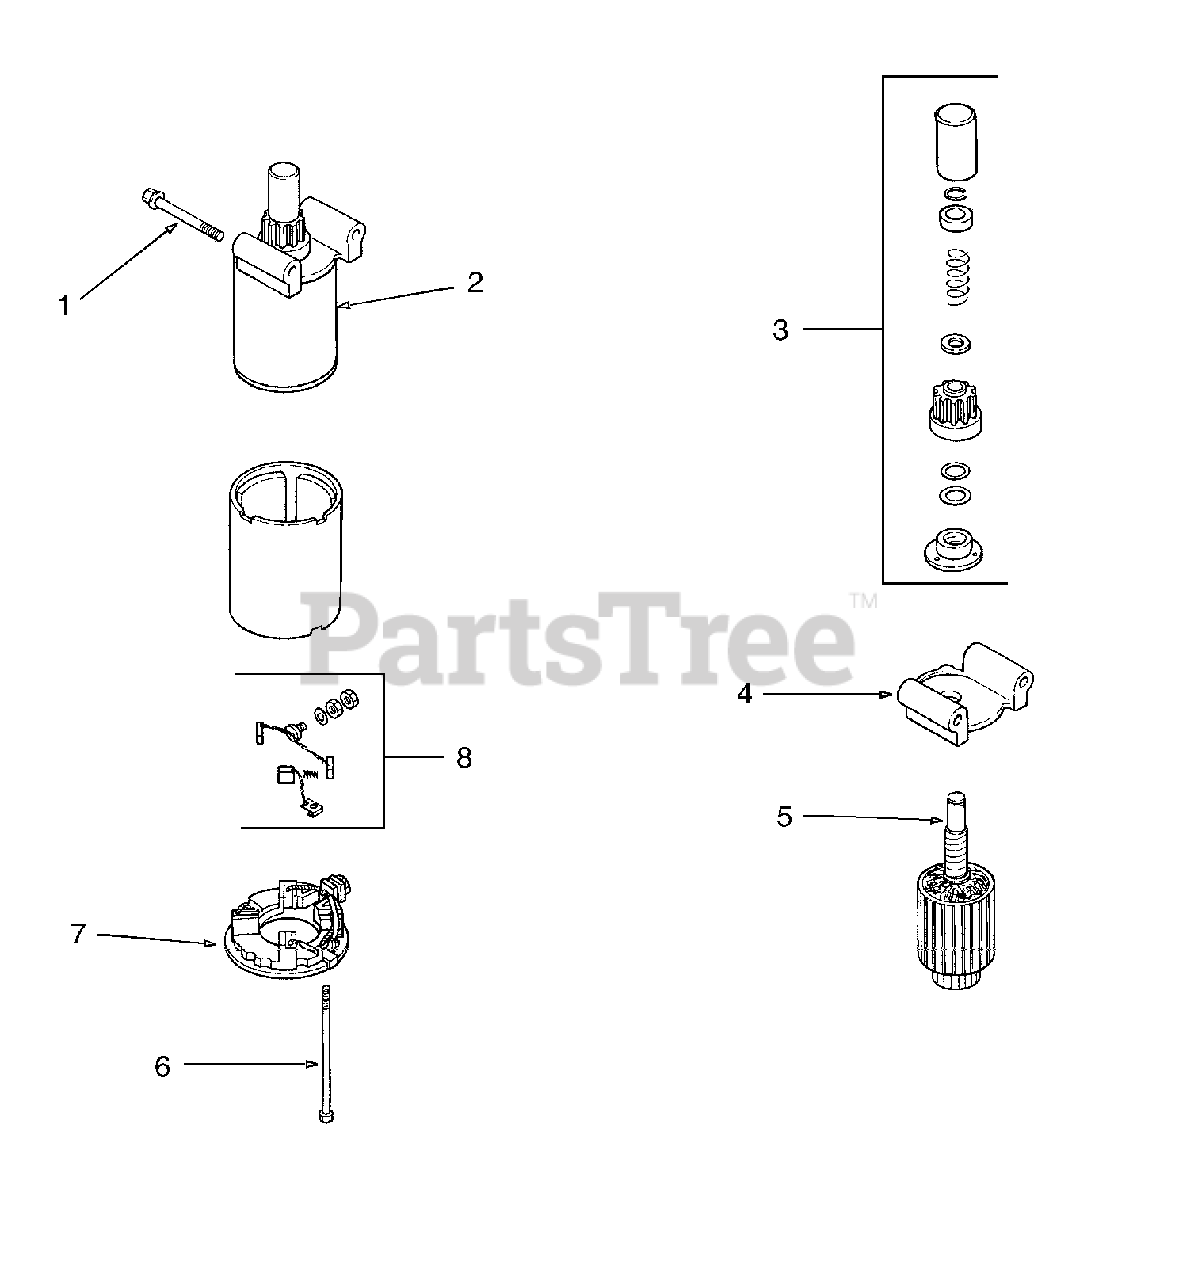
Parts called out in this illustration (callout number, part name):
1	Screw, Hex Flange, M8 x 1.25 x 70
2	Starter Assembly
4	Cap, End
6	Screw, Hex Flange, 1/4 - 20 x 4-5/8
7	Commutator, End Cap
8	Kit, Brush and Spring
